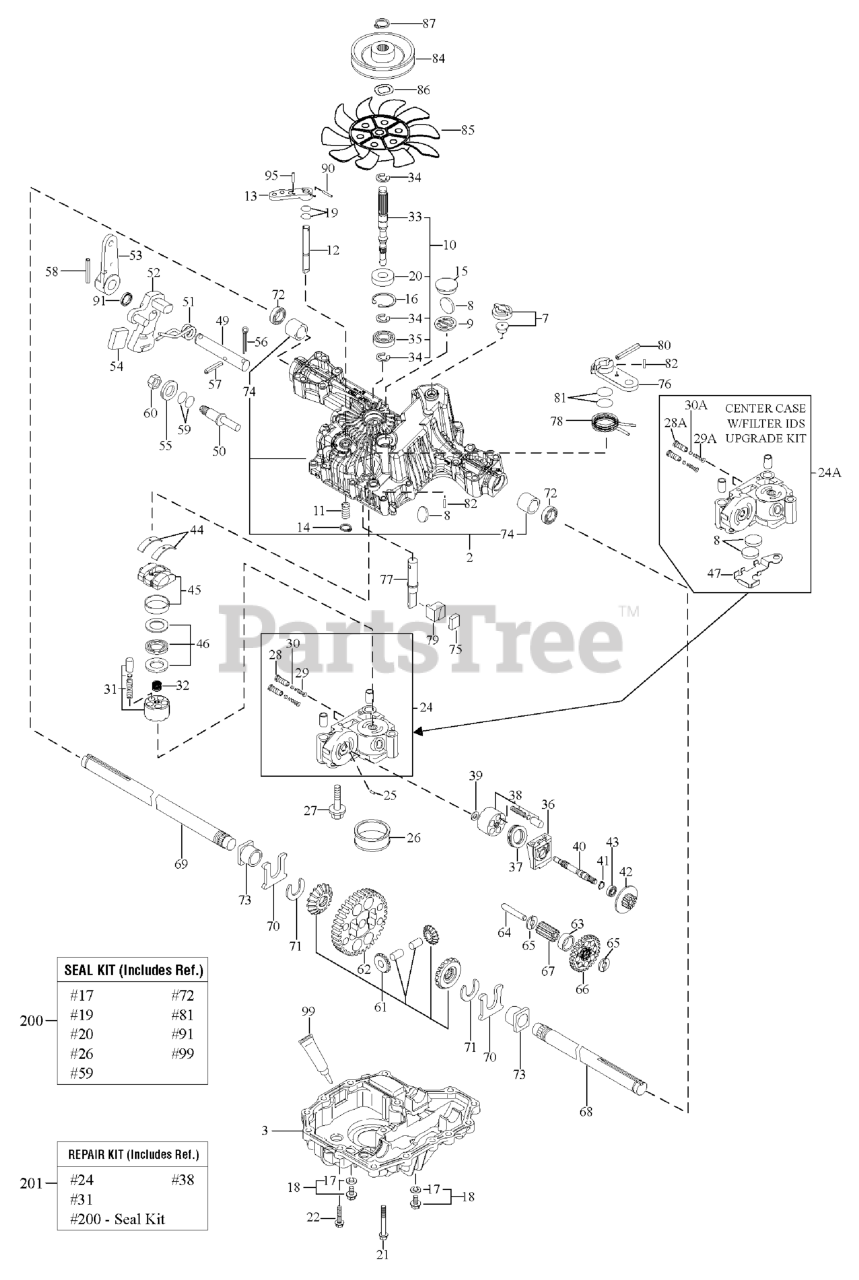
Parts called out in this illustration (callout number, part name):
1	TRANSMISSION ASSEMBLY, Tuff Torque, K46BL
2	KIT, Upper Case
3	LOWER CASE
7	VENT VALVE 15
9	*MAGNET HOLDER
10	*KIT, Pump Shaft/Bearing
12	BYPASS SHAFT A
13	LEVER, Bypass
14	RING, Snap, 10
15	SEALING CAP, 30
16	RING, Snap, C 35
17	SEAL WASHER, 8
18	KIT, Drain Bolt
19	0-RING, 1A P10A
20	SEAL TC 153507
22	SCREW, Tapping, 8 * 30
24	*CENTER CASE K W/ 1.2 FILTER IDS KIT
25	PIN, 3 * 9.8
27	BOLT, 10 * 75
29	*IDS SPRING
31	*KIT, Cylinder Block (Pump)
33	PUMP SHAFT
34	E-RING, 15
35	BEARING, 6202C3
36	MOTOR HOUSING
38	KIT, Cylinder Block
39	WASHER, 12 * 24 * 1
40	MOTOR SHAFT
41	RING, Snap, S15
42	BRAKE DISC/MOTOR GEAR (10T)
44	THRUST METAL
45	*SWASH PLATE CMP
46	THRUST BEARING K81105
49	*CONTROL SHAFT
50	*FULCRUM
51	*SPRING, Torsion
52	*CONTROL ARM A
53	CONTROL LEVER C
54	*JERKY PLATE
55	WASHER, 12
56	COTTER PIN, 1/8 * 3/4
57	SPRING PIN 6 * 36
58	ROLL PIN 6 * 40
59	O-RING 1A P14
61	*KIT, Diff Gear
63	*FINAL PINION COLLAR
64	*REDUCTION SHAFT
65	WASHER, 12 * 32 * 3.2
66	REDUCTION GEAR (38T)
68	AXLE SHAFT, Left
69	AXLE SHAFT, Right
70	THRUST WASHER
71	RING, 17
72	SEAL, 19 * 32 * 8
73	BUSHING, 19 * 25
75	BRAKE SHOE
76	BRAKE LEVER
77	*BRAKE SHAFT
78	*SPRING, Brake Return
79	BRAKE ACTUATOR
80	SPRING PIN, 5 * 32
81	O-RING 1A P12
82	SPRING PIN 4 * 16
84	PULLEY D
85	FAN, White
86	WASHER, Wave
87	RING, Snap
91	OIL SEAL 16 * 22 * .03
99	*SEALANT
200	*K46 & T40 SEAL KIT (ALL MODELS)
